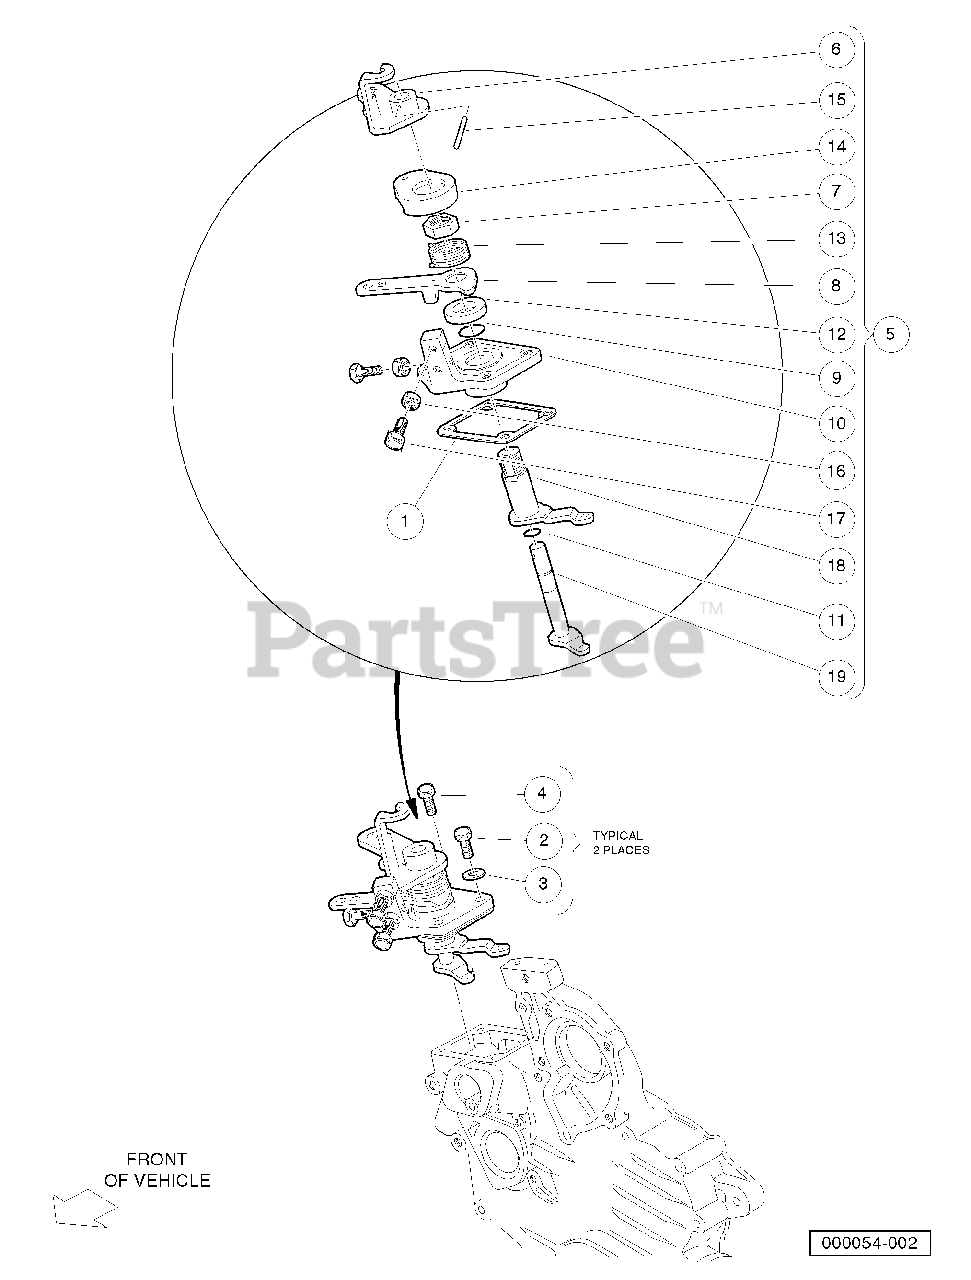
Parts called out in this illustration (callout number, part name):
1	Gasket, Control Plate
2	Bolt, M6 X 1 X 30
3	Gasket, 6 X 10
4	Bolt, D722 Intake Manfld Lower
5	Assembly, Speed Plate
6	Lever, Engine Stop
7	Nut, Speed Control
8	Lever, Speed Control
9	O Ring, 19 X 16
10	Plate, Speed Control
11	O Ring, 9 X 7
12	Collar, Lever
13	Spring, Return
14	Cap, Speed Cntrl Plate Rtrn
15	Pin, Spring, Speed Plate
16	Nut, Speed Control
17	Bolt, Speed Control
18	Lever, Governor
19	Shaft, Governor Lever
